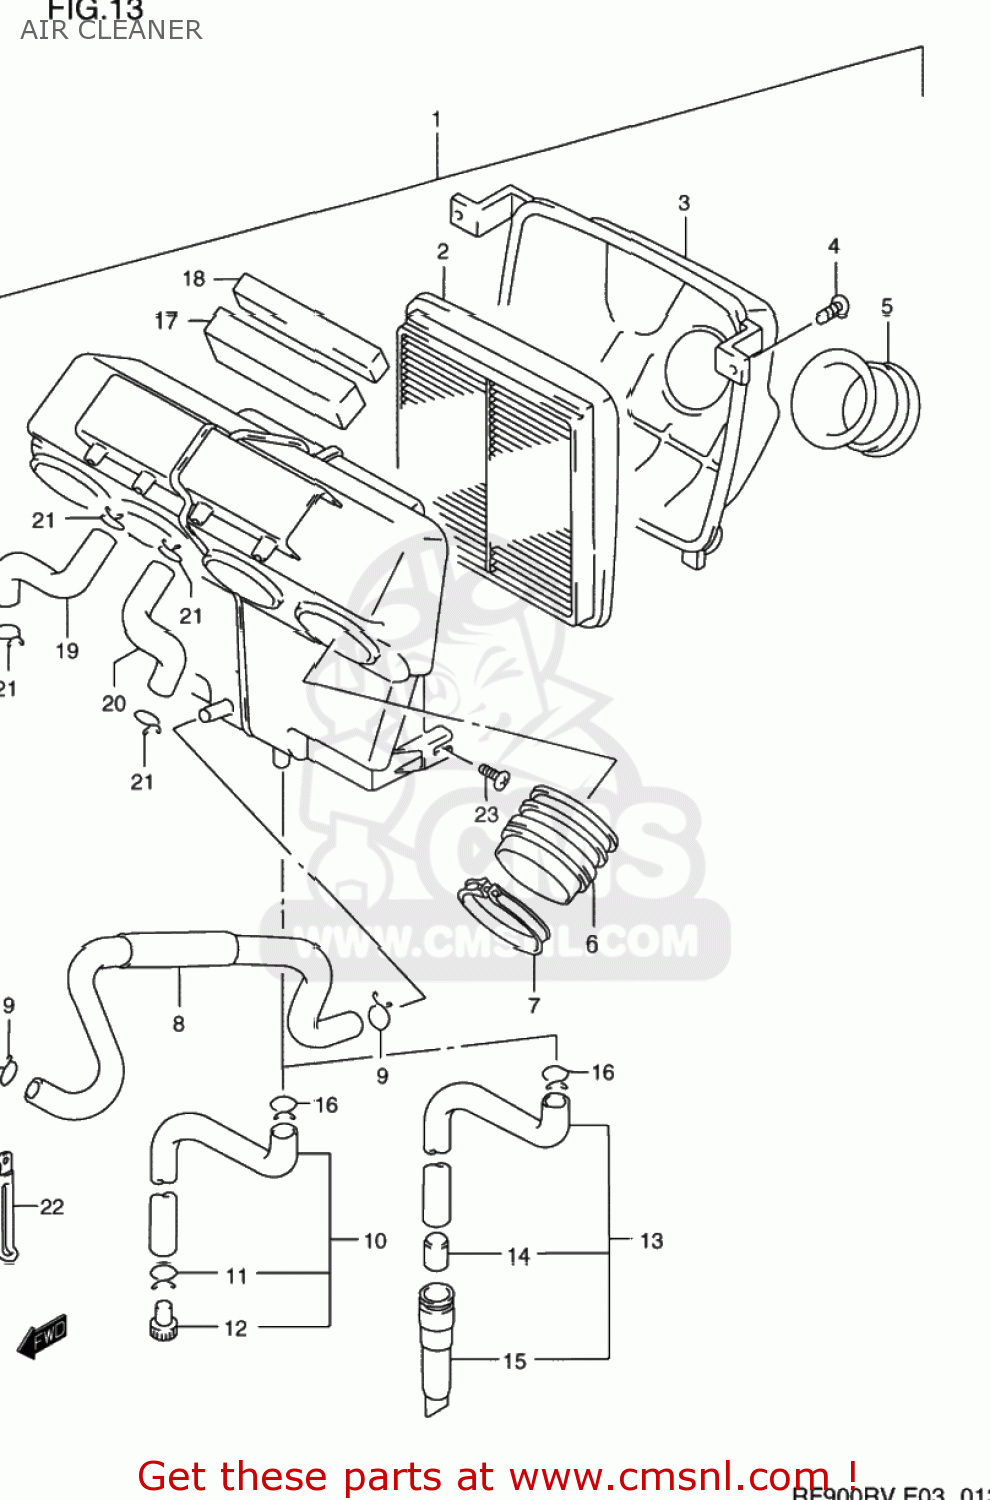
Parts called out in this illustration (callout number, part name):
1	CLEANER ASSEMBLY,AIR
2	FILTER,AIR
3	CAP,AIR CLEANER
4	SCREW
5	TUBE,INLET
6	TUBE,OUTLET
7	CLAMP
8	TUBE,BREATHER
9	CLIP
10	DRAIN TUBE
11	CLIP
12	STOPPER,DRAIN
13	TUBE,DRAIN
14	FILTER,DRAIN
15	CAP,DRAIN
16	CLIP
17	FILTER,CARB AIR
18	FILTER,AIR NO.2
19	TUBE,CARBURETOR AIR,R
20	TUBE,CARBURETOR AIR,LEFT
21	CLIP
22	CLAMP
23	SCREW 6X12
